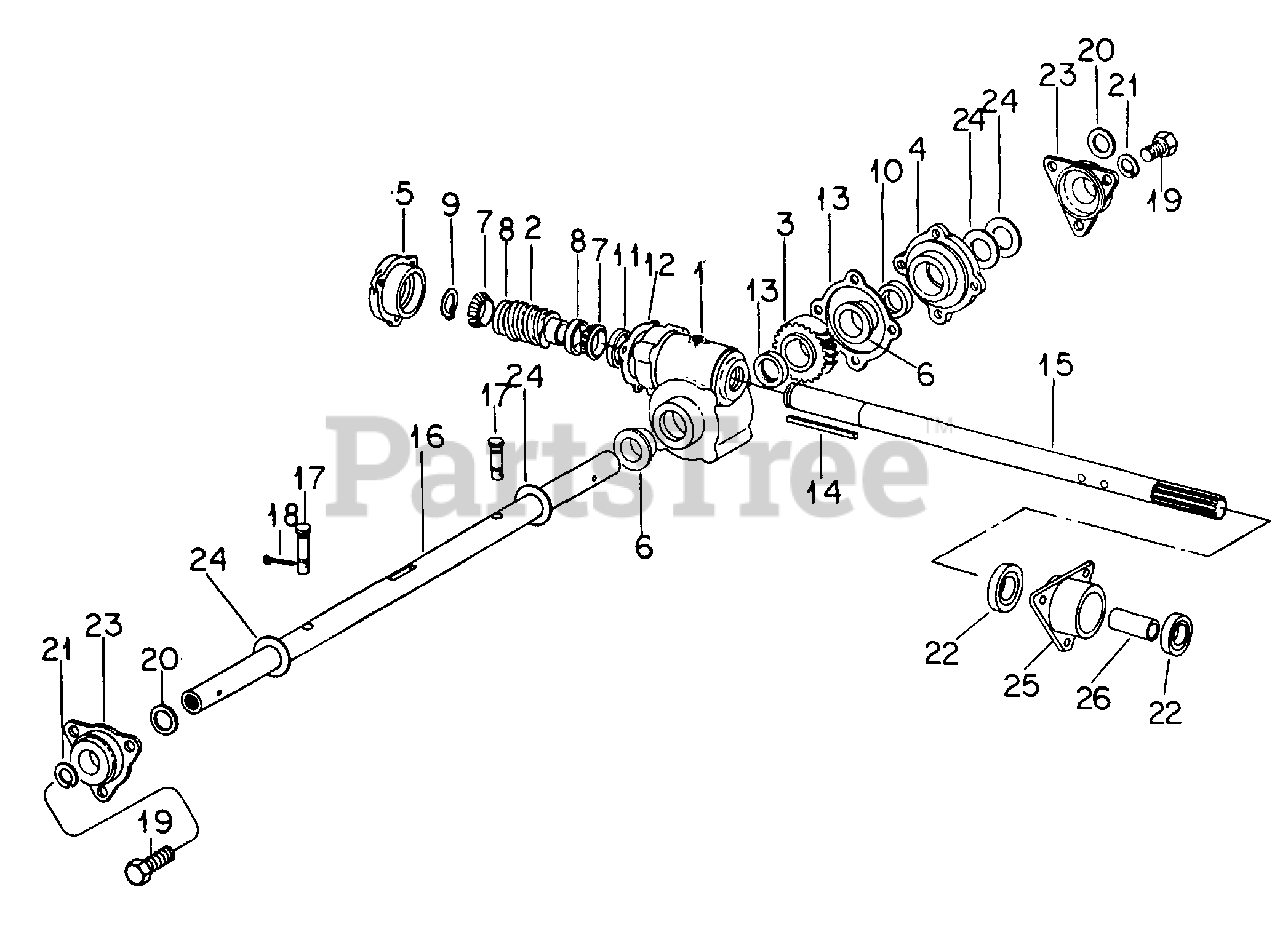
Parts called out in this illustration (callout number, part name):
2	WORM, DOUBLE THREAD
3	GEAR, LH - 20 TEETH
4	CAP, BEARING
5	CAP, BEARING
6	BUSHING, BRONZE
7	BEARING ASSY, ROLLER CONE
8	BEARING, ROLLER CUP
9	RING, RETAINING
12	SHIM, GASKET - .010
12	SHIM, GASKET - .020
13	SHIM, GASKET - .010
13	SHIM, GASKET - .020
14	KEY, 3/16 X 1-15/16 SQ PARALLEL
15	SHAFT, BLOWER
16	SHAFT, BLOWER
18	PIN, 5/32 X 3/4 COT.
19	SCREW, 1/2-13 X 1 HEX-HD CAP
20	WASHER, 17/32 X 1-1/4 X 16 GA
21	WASHER, 1/2 REG LOCK
22	BEARING, BALL
23	BEARING, FLANGE
24	WASHER, THRUST
25	SUPPORT, BLOWER SHAFT
26	SPACER, BEARING
